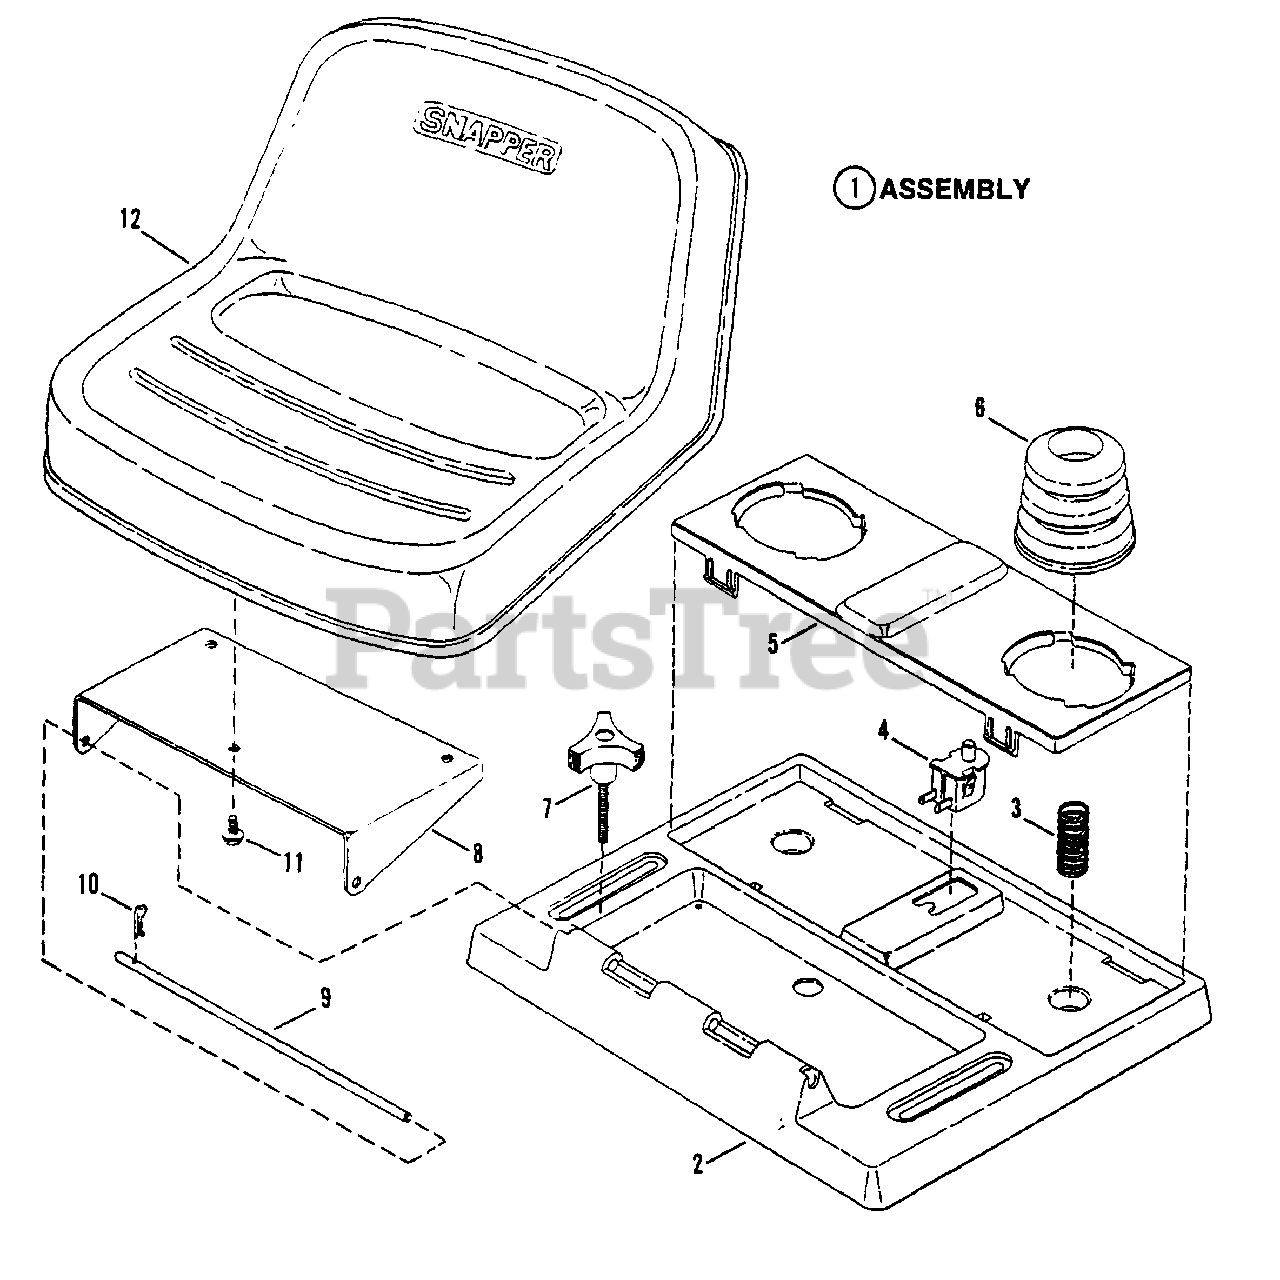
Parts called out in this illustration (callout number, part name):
1	ASSEMBLY, Seat Support
2	SUPPORT, Seat
3	SPRING
4	SWITCH, Seat
5	HOLDER, Cushion
6	CUSHION, Seat
7	KNOB, Seat Adjustment
8	BRACKET, Seat Support
9	ROD, Seat Hinge
10	PIN, Hair
11	BOLT, 5/16-18 x 1/2" Hex Range Lock
12	SEAT, Operator's
